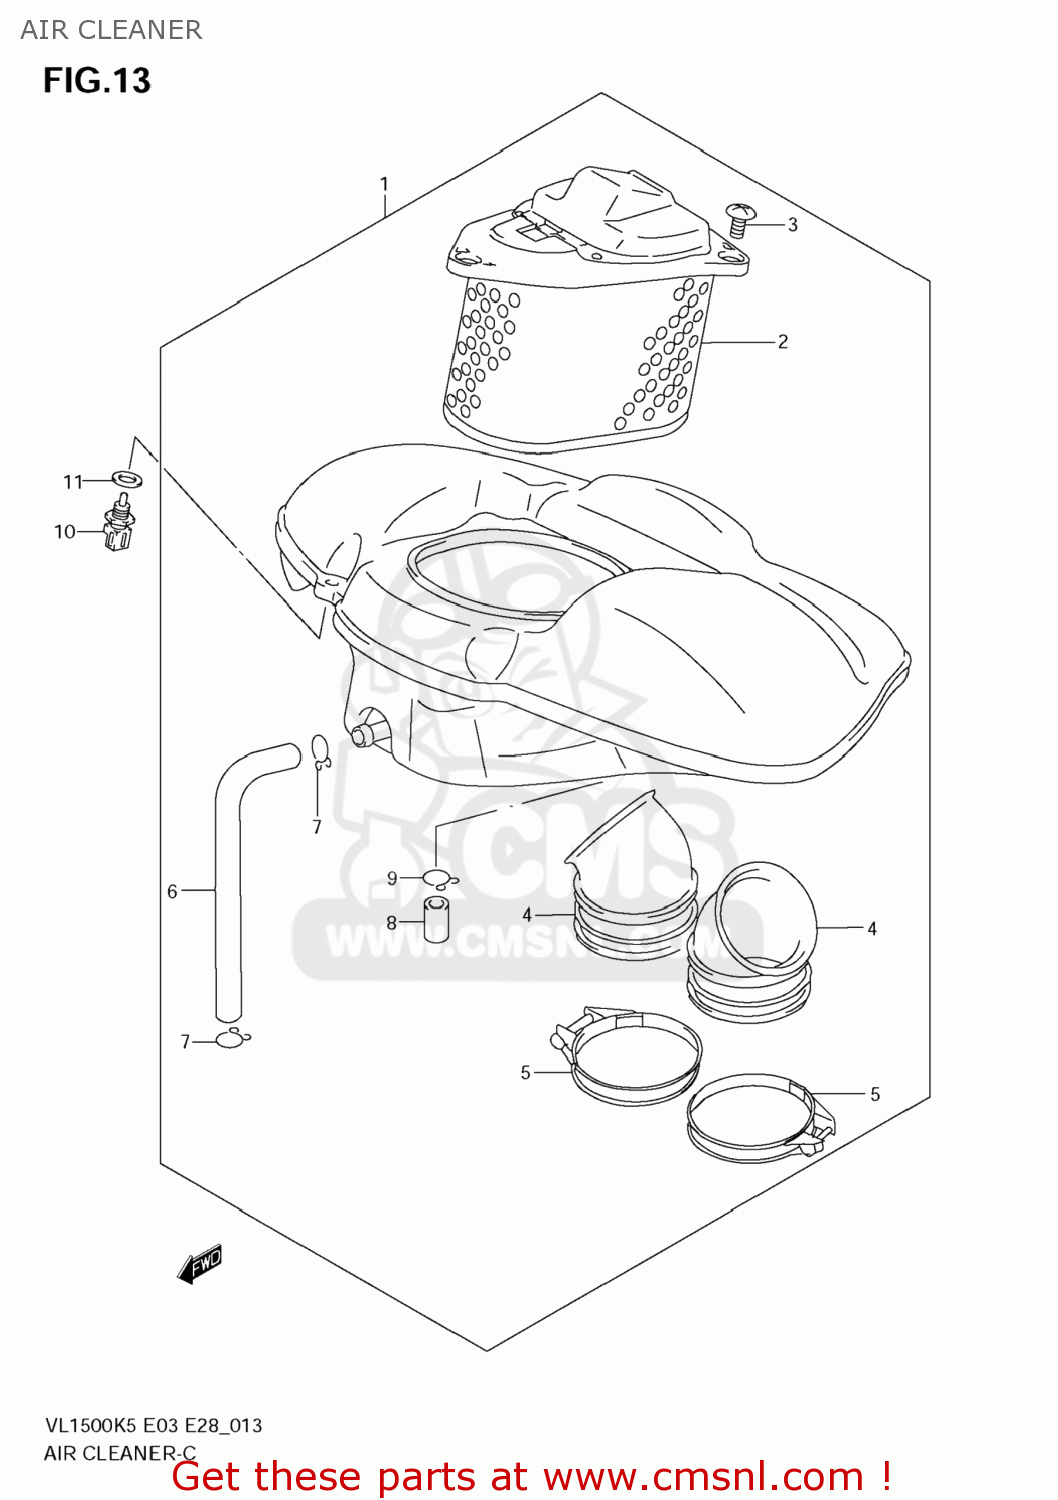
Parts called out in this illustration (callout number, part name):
1	CLEANER ASSY,AIR
2	FILTER
3	SCREW
4	TUBE,OUTLET
5	CLAMP
6	TUBE,BREATHER
7	CLIP
8	PLUG
9	CLIP
10	SENSOR,WATER TEMP
11	GASKET(12X17X1) (NAS)
